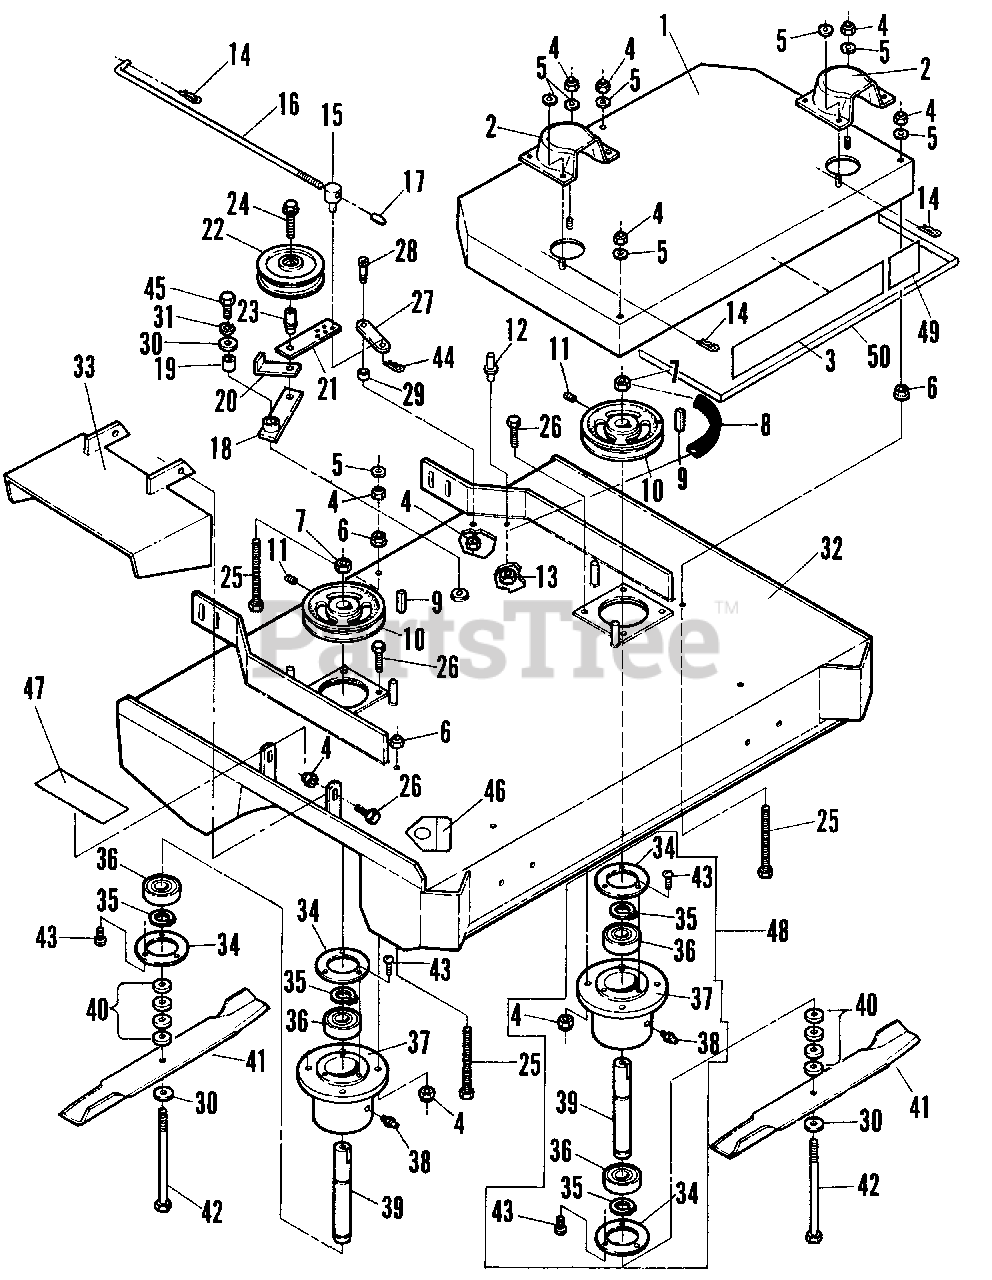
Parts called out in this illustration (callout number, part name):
1	BELT COVER W/DECALS 36
2	COVER, Spindle
3	DECAL, "SNAPPER"
4	NUT, 5/16-18 Nyloc Hex
5	WASHER, 5/16 Rd. Flat
6	NUT, 5/16-18 WHIZLOCK
7	NUT, 5/8 - 18 Hex
8	BELT, Engine Blade
9	KEY, 1/4 Square x 1 1/4
10	PULLEY, w/Set Screws
11	SCREW, Set
12	STUD, Stop
13	NUT, 3/8-16 w/H12 Lock
14	COTTER, #2 Hairpin
15	SWIVEL
16	ROD, Blade Drive
18	ARM, Idler w/Bushing
19	BUSHING
20	SNUBBER, Belt
21	ARM, Tightening
22	PULLEY, Idler
23	BUSHING, Flange
24	BOLT, Flange Lock 3/8-16 x 1 3/4
25	SCREW, Hex Head Cap 5/16-18 x 3 1/4
26	SCREW, Hex Head Cap 5/16-18 x 1 GR. 5
27	ARM, Blade Assist
28	BOLT, Knurled Socket Head Shoulder 3/8 x 3/4
30	WASHER, Flat 5/8
31	WASHER, Lock 5/8
32	DECK, Front 36 w/Decals
33	DEFLECTOR, Chute
34	CAP, CUTTER HOUSING
35	RING, RETAINING
36	BEARING (SINGLE SEAL)
37	HOUSING, CUTTER
38	ZERK, 1/8 NPT
39	SPINDLE, CUTTER
40	SPACER, Blade
41	BLADE 18 HIGH LIFT (.204)
42	SCREW, Hex Head Cap 5/8-18 x 7 1/2
43	SCREW, SELF-TAPPING 10 - 24 x 1/2
44	COTTER, Hairpin #4
45	SCREW, Hex Head Cap 5/8-11 x 1
46	DECAL, CPSC
47	DECAL, "Caution"
48	ASSEMBLY CUTTER HOUSING
49	DECAL, 36 Inch
50	DECAL, STRIPE
